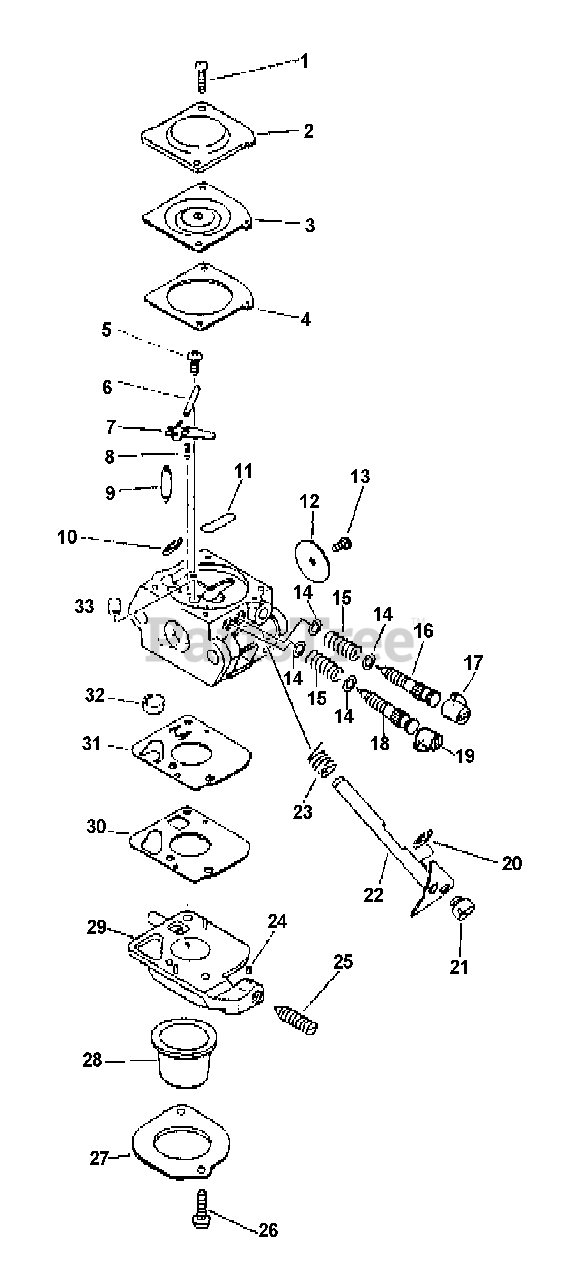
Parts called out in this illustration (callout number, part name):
2	COVER, METERING DIAPHRAGM
3	DIAPHRAGM, METERING
4	GASKET, METERING
6	PIN, METERING LEVER
7	LEVER, METERING
8	SPRING, METERING LEVER
9	VALVE, NEEDLE
11	PLUG, WELCH
12	VALVE, THROTTLE
15	SPRING, NEEDLE
16	NEEDLE, IDLE
17	CAP, LIMITER - WHITE
18	NEEDLE, HIGH SPEED
19	CAP, LIMITER - RED
22	SHAFT, THROTTLE
23	SPRING, THROTTLE RETURN
24	PIECE, FRICTION
25	SCREW, IDLE ADJUST
27	RETAINER
28	BULB, PURGE
29	BODY ASSY, PURGE
32	STRAINER
33	NOZZLE, CHECK VALVE
